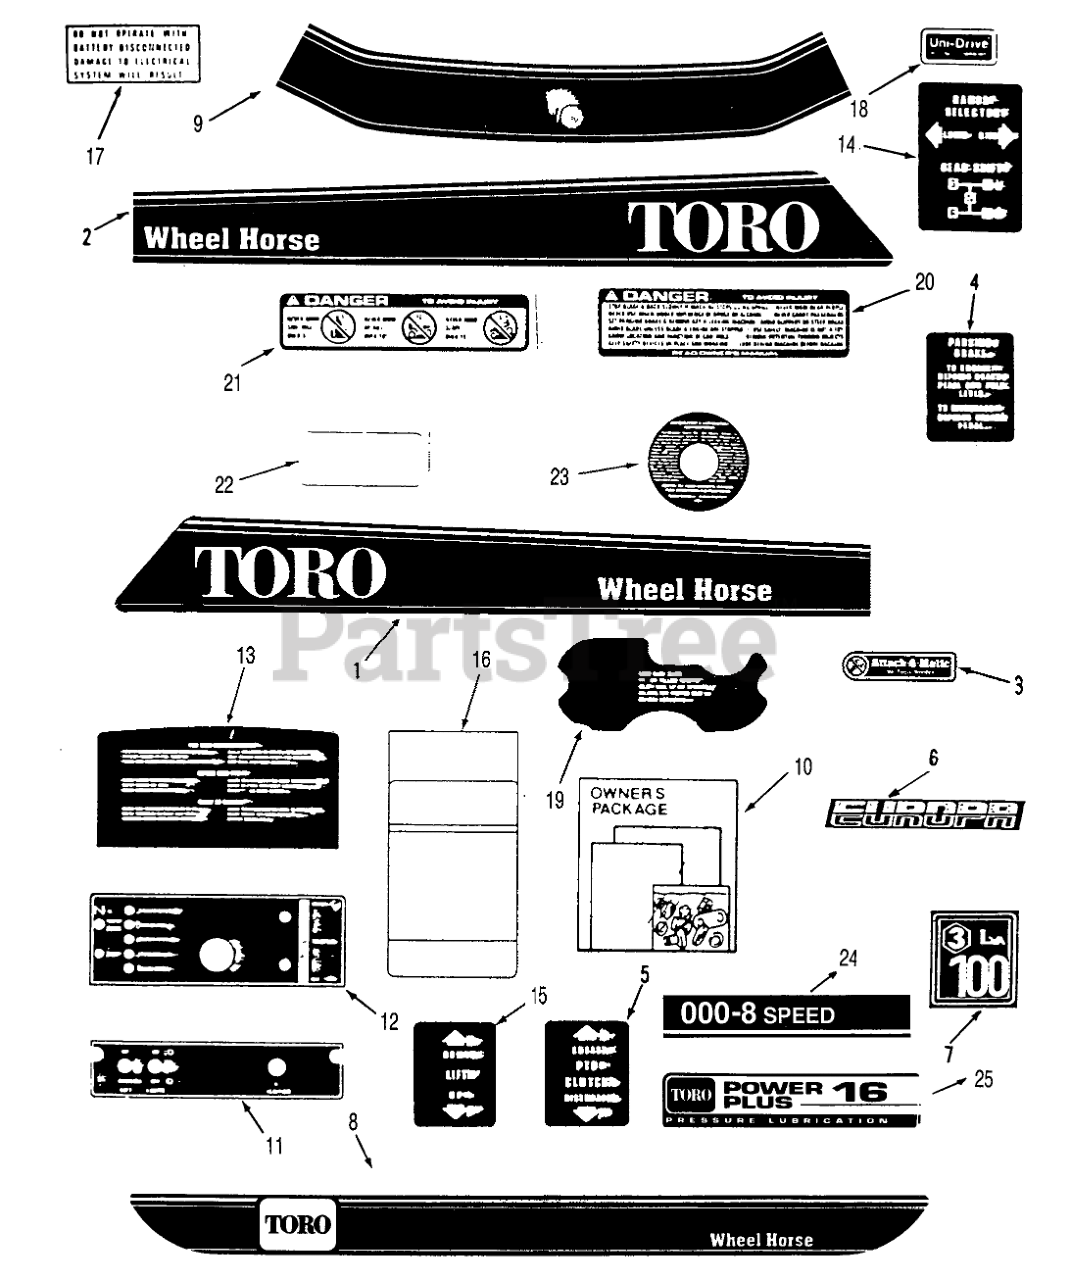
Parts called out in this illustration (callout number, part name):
1	DECAL-HOOD CLASSIC
2	DECAL-HOOD GEN 26.20
3	Decal-Attac-O-Matic
4	DECAL-PARKING, BRAKE
5	DECAL PTO CLUTCH
6	DECAL-EUROPA
7	DECAL-EUROPE
8	DECAL-FENDER
9	DECAL-FRONT HOOD
10	Loose Parts Package 310-8, 312-8
11	Decal-Switch Plate
12	DECAL-LOWER DASH
13	Decal-Rear Hood
14	DECAL-SHIFT PATTERN
15	DECAL-LIFT
16	MAINTENANCE-DECAL
17	DECAL ELECT SYSTEM
18	Decal-Unidrive
19	DECAL-SEAT LIFTER
20	Decal-Danger
21	Decal-Danger
22	DECAL-OVERLAY
23	Decal-Air Cleaner
24	DECAL-312 8-SPEED
25	DECAL-PWR PLUS 16 PL
